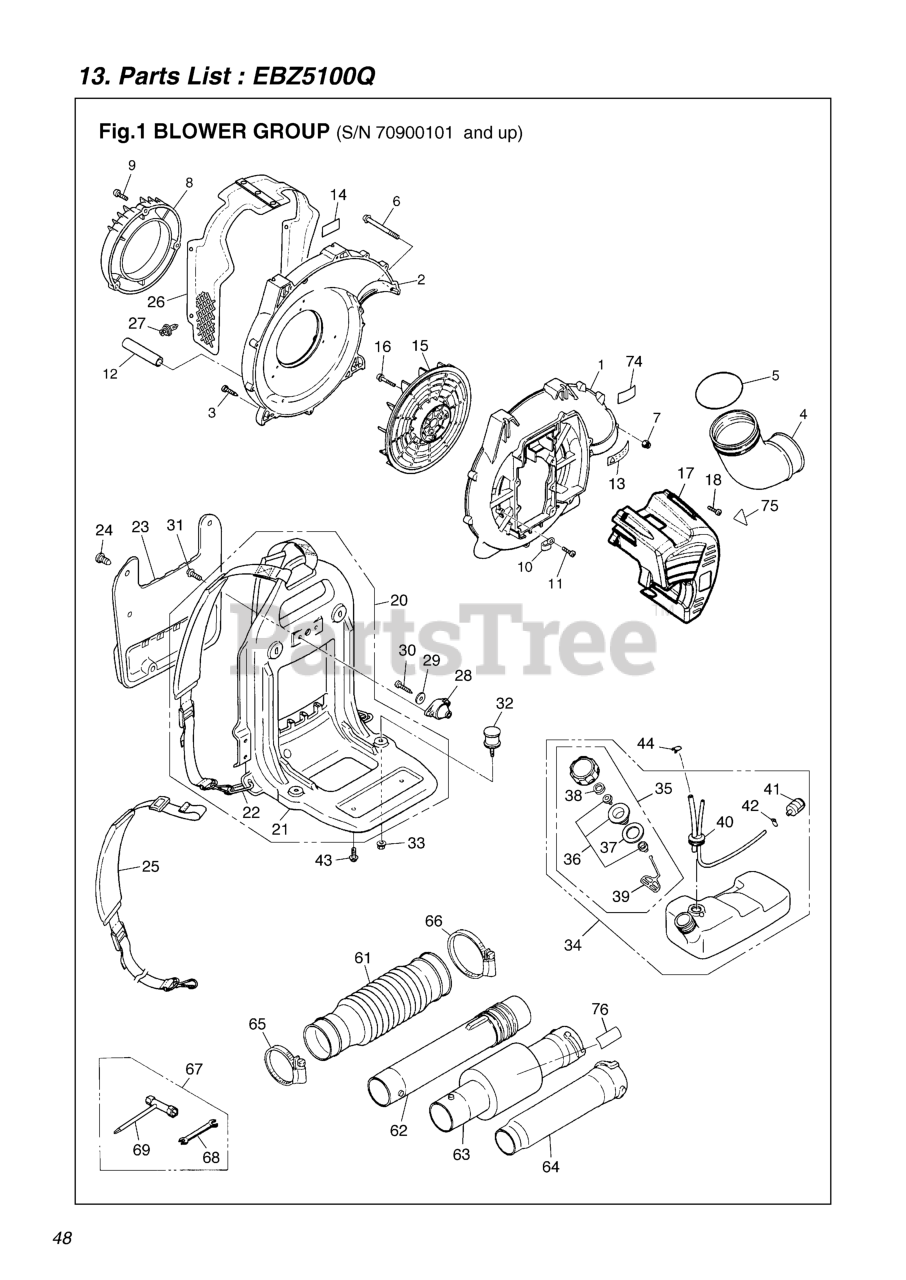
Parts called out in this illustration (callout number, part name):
1	VOLUTE CASE
2	VOLUTE COVER
3	SCREW
4	ELBOW
5	O-RING
6	SCREW
7	NUT
8	FUNNEL
9	SCREW
10	CLAMP
12	TUBE
13	LABEL
14	LABEL, NET
15	FAN
16	BOLT
17	ENGINE COVER
18	SCREW
20	FRAME ASSY
21	FRAME COMP
22	RING
23	PAD
24	CLIP
25	BAND ASSY
26	NET COMP
27	CLIP
28	DAMPER, UPPER
29	WASHER
30	SCREW
31	SCREW
32	DAMPER, LOWER
33	NUT
34	TANK ASSY
35	CAP ASSY
36	HOLDER ASSY
37	PACKING
38	FILTER
40	PIPE COMP
41	FILTER ASSY
42	CLIP
43	SCREW
44	CLIP
61	HOSE
62	SWIVEL JOINT
63	PIPE, SILENCER
64	PIPE, END
65	CLAMP
66	CLAMP
67	TOOL-SET
68	SPANNER
74	LABEL, SOUND
75	LABEL, HOTMARK
76	LABEL, SILENCER
